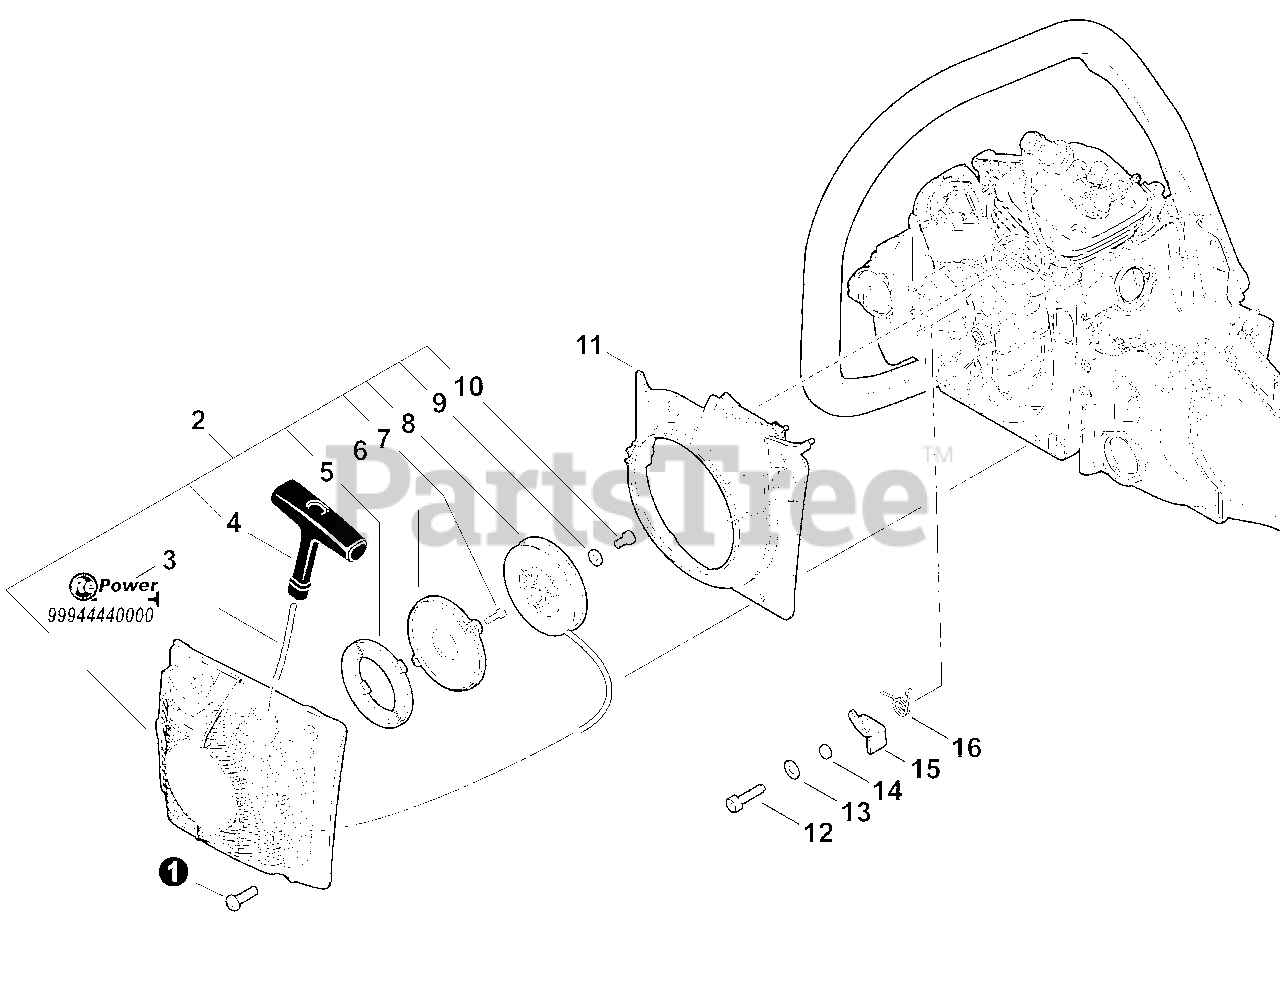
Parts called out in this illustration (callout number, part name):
1	SCREW - 5×20
2	STARTER ASY
3	ROPE, STARTER - 4×950
4	GRIP, STARTER
5	SPRING, REWIND
6	PLATE, STARTER
7	SCREW - 4×12
8	REEL, ROPE
10	SCREW - 5×10
11	COVER, FAN
12	SCREW - 5×16
13	WASHER - 5.5×12
15	PAWL, STARTER
16	SPRING, RETURN
